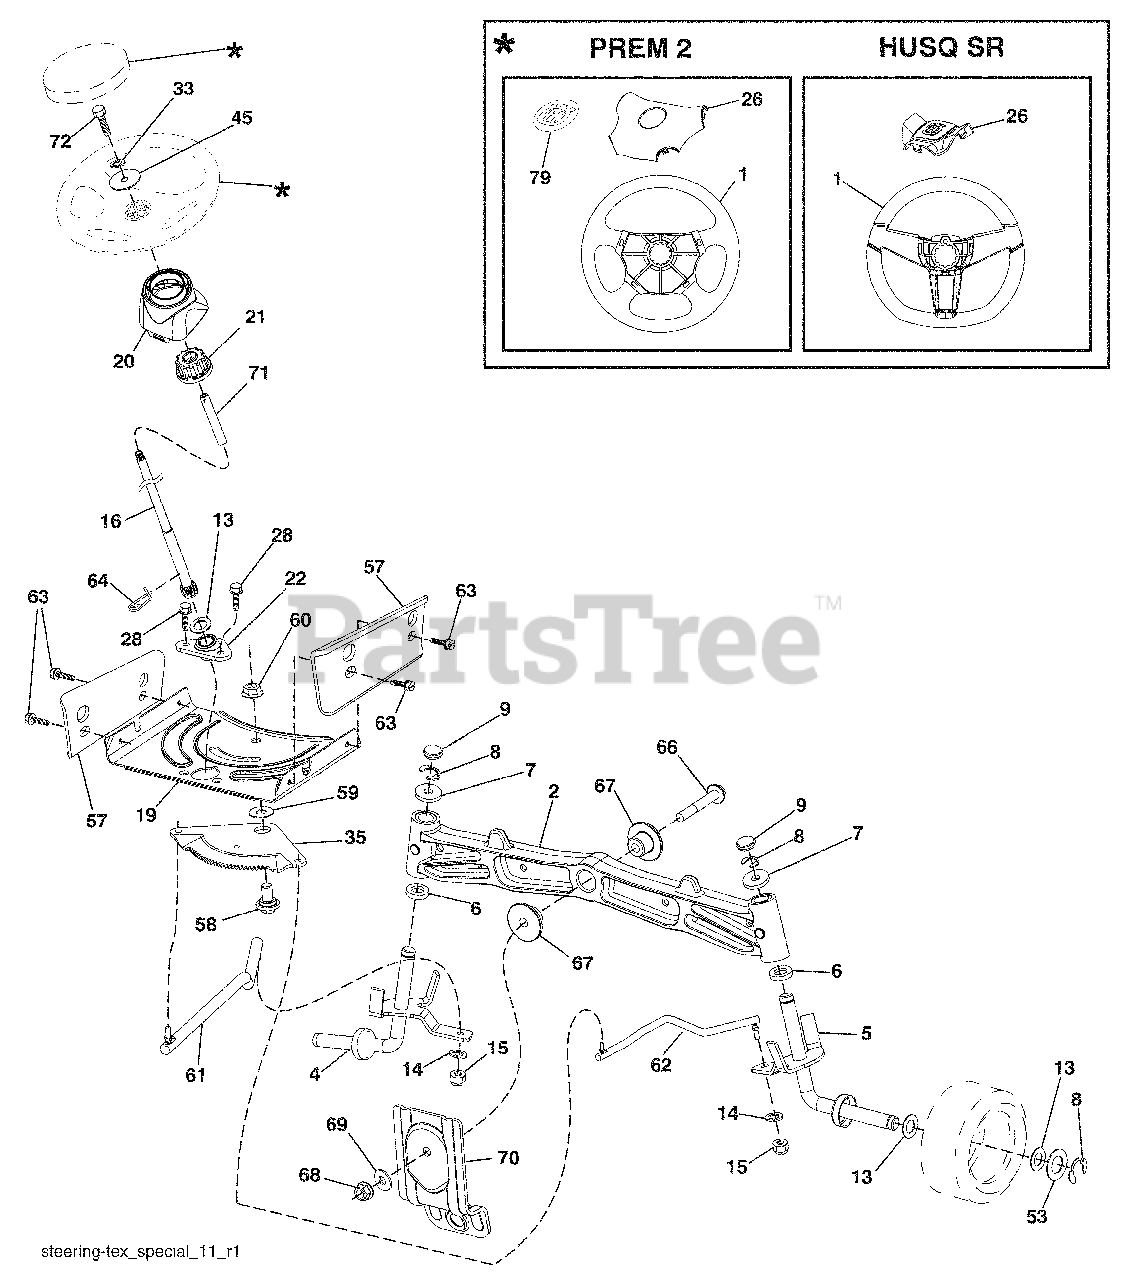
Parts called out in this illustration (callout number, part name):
1	Wheel, Steering
2	Axle Asm., Front
4	Spindle Asm., LH
5	Spindle Asm., RH
6	Bearing, Race Thrust Harden
7	Washer 25/32 x 1-5/8 x 16 Ga.
8	Ring, Klip #T5304-75
9	Cap, Spindle
13	Washer 25/32 x 1-1/4 x 16 Ga.
14	Washer, Lock Hvy Hlcl Spr 3/8
15	Nut, Crown Lock 3/8-24 unf
16	Shaft Steering
19	Plate Steering
20	Boot, Steering
21	Adapter, Wheel Steering
22	Bushing, Strg. Blk
26	Insert, Wheel Steering
28	Screw 3/8-16 x 3/4
33	Washer Lock 5/16
35	Gear, Sector Plate
45	Washer 11/32 x 3/8 x 12 Ga.
53	Washer Hardened .793 x 1.637 x .060
57	Bracket Upstop
58	Bolt Shoulder Sector Pivot CFM
59	Washer Thrust Sector Steering
60	Nut Flange Lock 5/8-11
61	Draglink, LH
62	Draglink, RH
63	Screw 5/16-18 x 3/4
64	Retainer Clip Spring Steering
66	Bolt Hex Fghd 7/16-14 x 3 Serr
67	Bushing PM Front Axle
68	Nut Lock Flange 7/16-14 Gr. 5
69	Washer 1.5 x .505 x .118
70	Bracket Deck Susp. Front
71	Shaft Extension Steering
72	Bolt 5/16-18 unc x 4.5. Gr. 5
